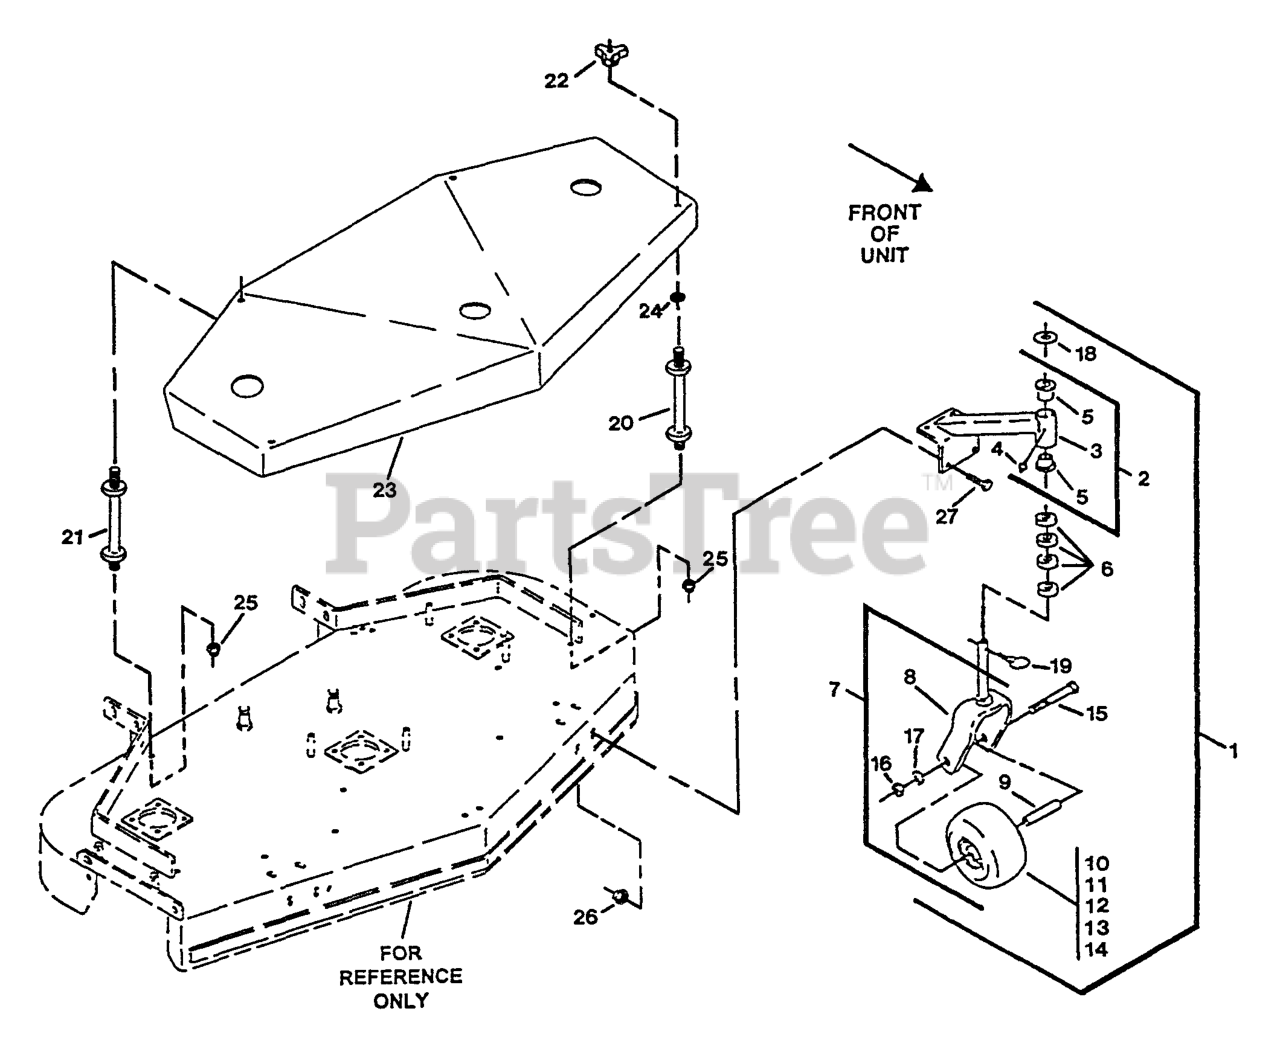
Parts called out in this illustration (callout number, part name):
1	CASTER/MOUNT ASM
2	SUPPORT ASM
5	BEARING-FLANGED
6	SPACER-CASTER
13	BEARING
14	BUSHING
18	WASHER-FLAT
20	STUD-SHIELD, BELT (SHORT)
21	STUD-SHIELD, BELT (LONG)
22	KNOB-3 PRONG
23	ASM,SHIELD BELT 48
